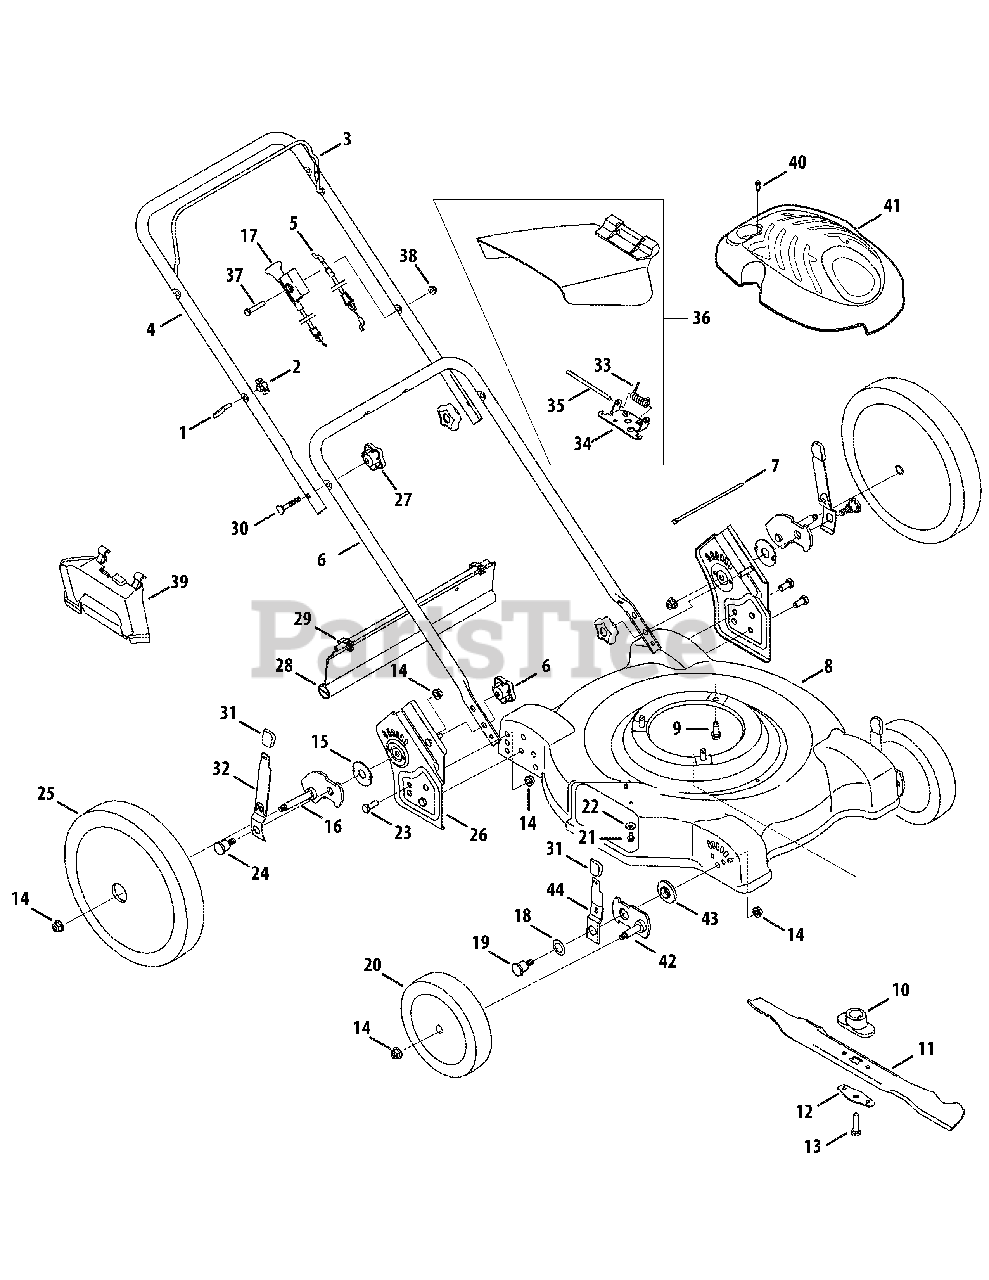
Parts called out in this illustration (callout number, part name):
1	Eye Bolt
2	Wing Nut
5	Control Cable
7	Cable Tie
9	TT Screw, 3/8-16 x 1.0
10	Blade Adapter
11	Muliching Blade, 22''
12	Blade Bell Support
13	Screw, 3/8-24 x 1.5
14	Lock Nut, 3/8-16
15	Thrust Bearing
16	Rear Pivot Arm - LH
16	Rear Pivot Arm - RH
17	Choke Cable
18	Bell Washer, .760 OD x 1.25 OD
19	Shoulder Screw
20	Front Wheel
21	TT Screw, 1/4-20 x .5
22	Bell Washer, .265 ID x .75 OD
23	Screw, 3/8-16 x .75
24	Shoulder Screw
25	Rear Wheel
28	Trailshield
29	Hinge Clip
30	Carraige Bolt, 5/16-18 x 2
31	Knob
32	Rear Lever
33	Torsion Spring
34	Chute Hinge
35	Hinge Pine
36	Hinged Chute Deflector Assembly
37	Screw, 1/4-20 x 1.50
38	Flange Lock Nut, 1/4-20
39	Mulching Baffle
40	Machine Screw M4-.7
41	Engine Shroud
42	Front Pivot Arm
43	Height Adjuster Bearing
44	Front Lever
